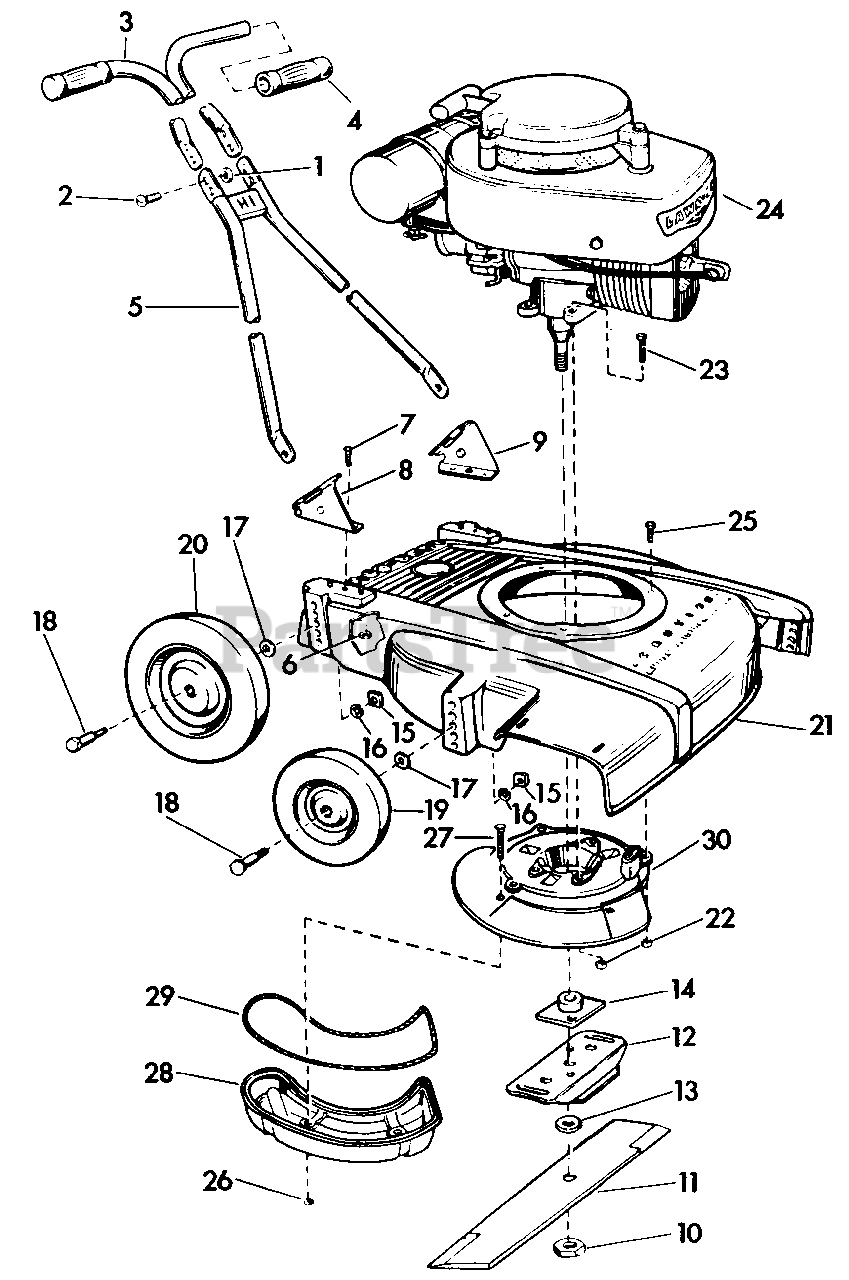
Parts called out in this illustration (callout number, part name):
1	Nut-Handle
2	Screw-Handle
3	Handle Assembly-Top
4	Grip-Handle
5	Handle Assembly-Bottom
6	Nut-Nylon, Handle Bracket
7	Screw-Handle Bracket
8	Bracket-Handle, Right
9	Bracket-Handle, Left
10	Nut-Blade
11	Blade-18"
11	Blade-21"
12	Stiffener-Blade
13	Fiber Washer (21" Model only)
14	Collar and Plate Assembly
15	Nut-Wheel
16	Washer-Lock, Wheel
17	Washer-Plain, Wheel
18	Bolt-Shoulder, Wheel
19	Wheel Assembly, 6 x 1.50
20	Wheel Assembly, 8 x 1.75
21	Housing-18"
21	Housing-21"
22	Nut-Nylon, Muffler Plate and Engine Mounting
23	Screw-Engine Mounting
24	Engine-Model C-70
25	Screw-Muffler Plate
26	Nut-Lock, Muffler Bolt
27	Bolt-Muffler
28	Muffler
29	Gasket-Muffler
30	Plate-Muffler
